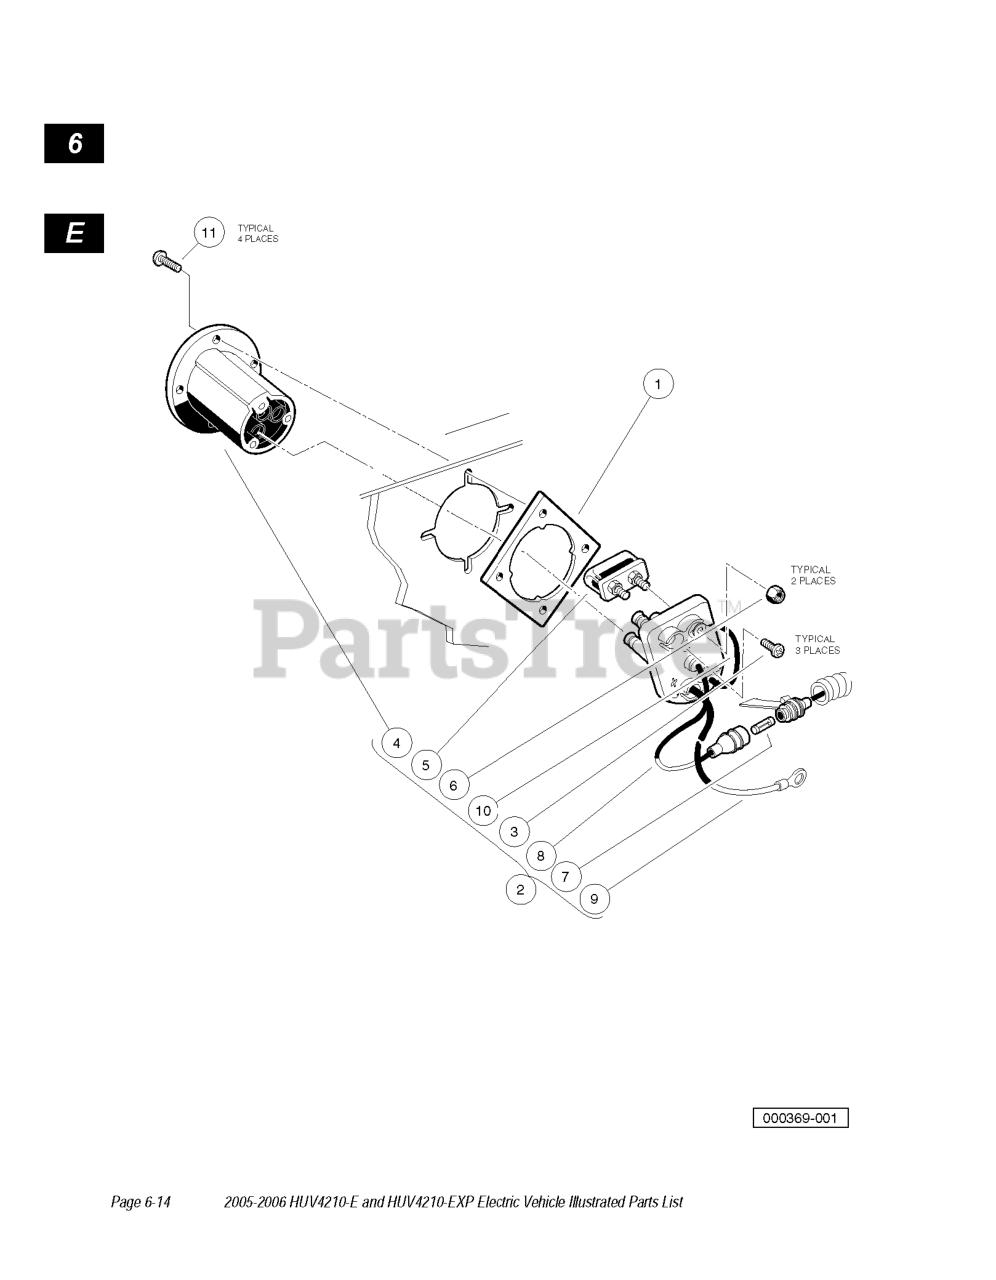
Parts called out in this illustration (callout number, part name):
1	PLATE RECEPTACLE BLACK
2	FUSE & RECEPTACLE ASSEMBLY
3	SCREW #8X5/8 PHIL PAN HD AB
4	RECEPTACLE FOR MOLDED PLUG
5	FUSE ASSEMBLY
7	3/8 AMP FUSE
11	SCREW, #7-19 X .625 PHL PN TAP
